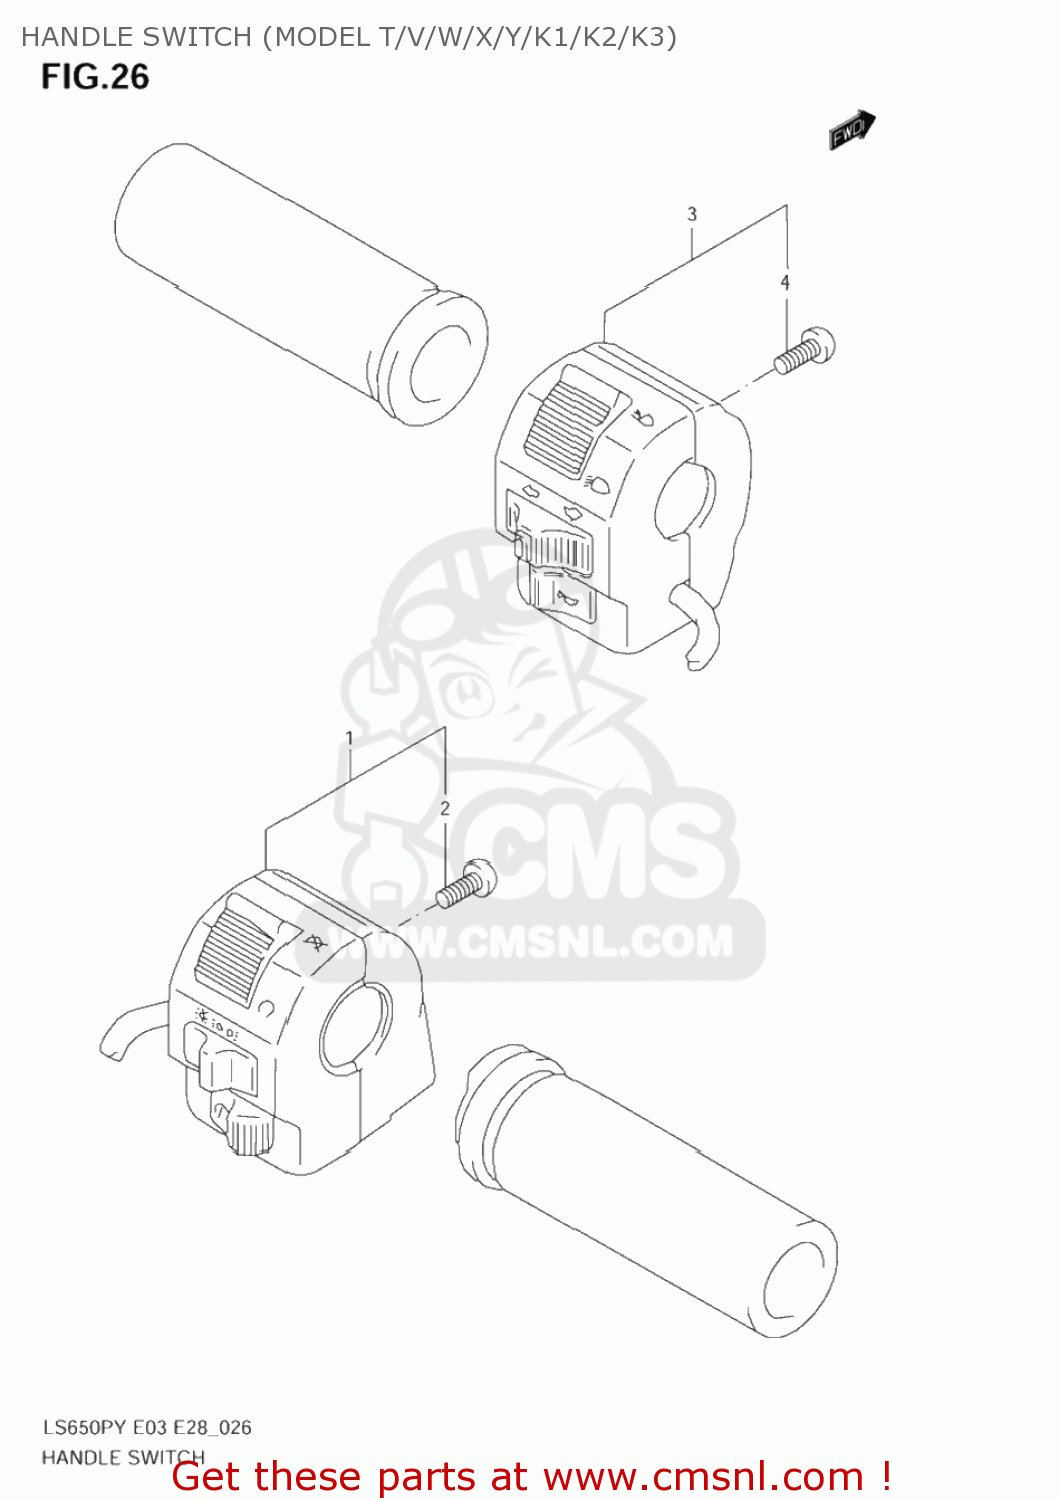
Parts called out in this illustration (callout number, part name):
1	SWITCH ASSY,HANDLE,R
2	SCREW
3	SWITCH ASSY,HANDLE,L
4	SCREW
